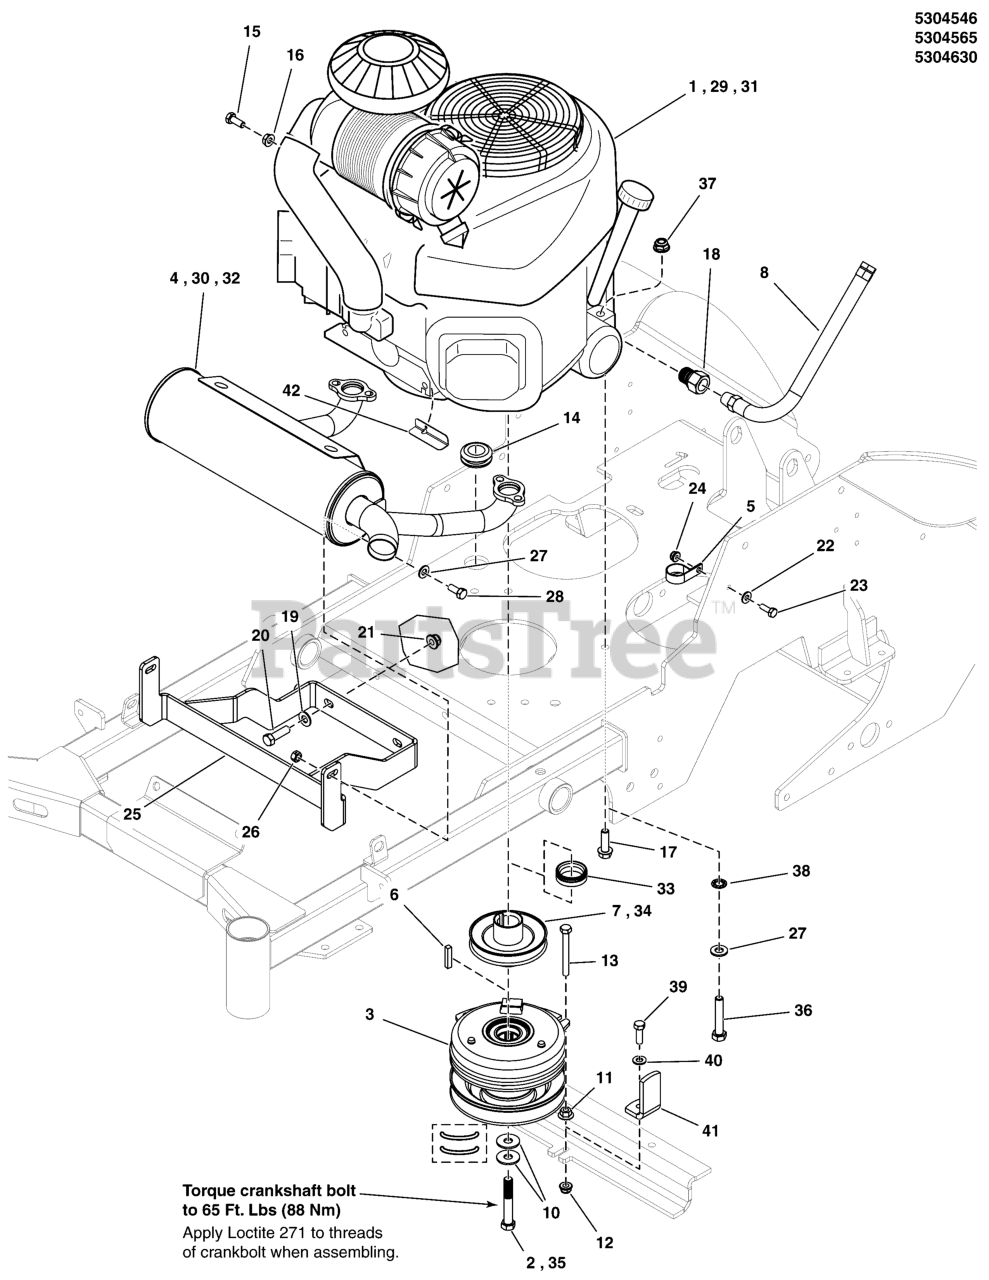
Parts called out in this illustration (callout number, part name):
2	BOLT, CRANKSHAFT, 7/16 X 2-3/4, PATCH, CZ
3	CLUTCH, WARNER, 125 FTLBS - 1.13"
4	MUFFLER, 15-19HP KAWI, CATALYTIC COMBUST
4	MUFFLER 15-19HP KAWI
5	CLAMP, VINYL INSULATED, 1.00
6	KEY, 1/4" SQ. X 1-1/4
7	PULLEY, CRANKSHAFT, 1.1255 ID X 4.00 OD
8	HOSE, OIL DRAIN
9	TIE,SELF-LOCKING, 24"
10	BELLEVILLE WASHER, 1.1875 X .442 X .098
11	NUT, 5/16-18 HEX SERRATED FLANGE (LARGE)
12	NUT, 5/16-18 HEX NYLOCK FLANGE NUT
13	BOLT, 5/16-18 X 2-3/4, GD 5, YZ
14	GROMMET, 7/8"ID, 1/4" THICK STK
15	BOLT, M8-1.25 X 16MM GD8.8
16	NUT, M8-1.25 Hex Serrated Flange
17	BOLT, HEX FLG, SER, GD5 3/8-16 X 1-1/4" PACH CZ
18	ADAPTER, Oil Drain
19	WASHER, 3/8 SAE
20	BOLT, 3/8-16 X 1-1/4" GD5 CZ
21	NUT, 3/8 - 16 HEX NYLOCK FLANGE
22	WASHER, 1/4 SAE
23	BOLT, 1/4"-20 X 3/4" GD5 YZ
24	NUT, 1/4-20 Hex Nylock Flange
25	WELD, EXHAUST SUPPORT BRACKET - BLK
26	NUT, 5/16-1/8, HEX, CNTR LK, ZINC PHOS/OIL
27	WASHER, 5/16" SAE
28	BOLT, 5/16-18 X 3/4 GD5
30	MUFFLER, HORIZONTAL, KAWASAKI
30	MUFFLER 22 HP KAWI CATALYTIC COMBUSTION
31	ENGINE, 23HP, BRIGGS VANGUARD
32	MUFFLER, 23HP BRIGGS VANGUARD, SRSZ1
32	MUFFLER 23HP VANGUARD SRSZ1 (SHORT)
33	SPACER, 1.50 X 1.125 X .50, CZ
34	PULLEY,CRANKSHAFT,1.1255IDX4.00OD,BRIGGS
35	BOLT, CRANKSHAFT, 7/16-20 X 3, GD8
36	BOLT, 5/16-24 X 1-3/4, GD8, PHOS
37	NUT, 5/16-24, TOP LOCK FLANGE, GD8 PHOS
38	WASHER, 5/16" Internal Tooth Lock
39	BOLT, 5/16-18 X 1" GRD5 YZ
40	WASHER, 5/16" SAE
41	PLATE, CLUTCH ANCHOR, Z1 - BLK
42	PLATE, SS HEAT SHIELD, Z1-BRIGGS
